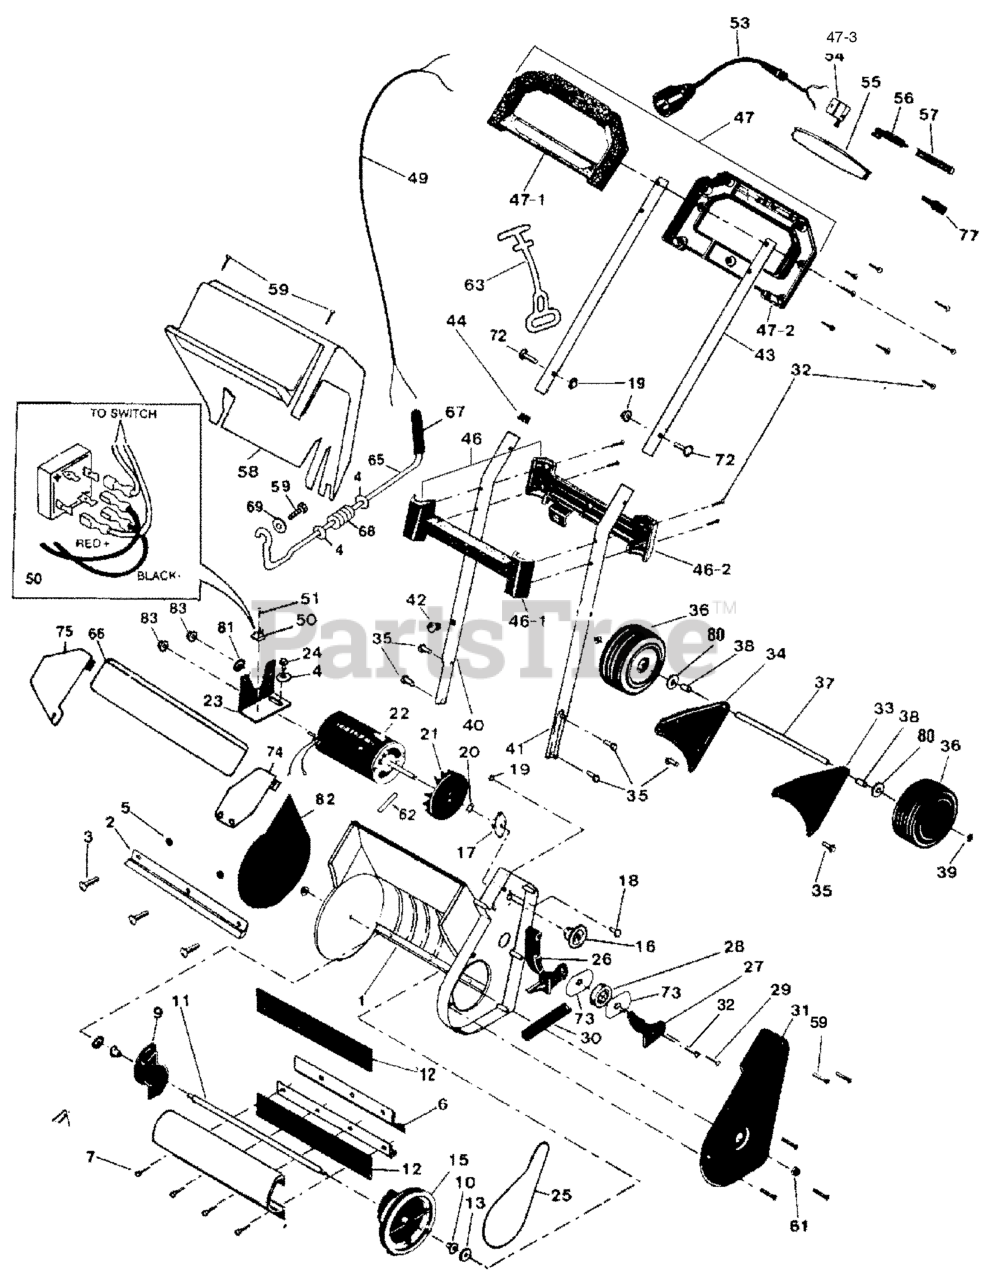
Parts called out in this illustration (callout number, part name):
1	Housing, Scoop
2	Blade, Scraper
4	Washer, Flat
5	Nut, 1/4-20
6	Segment, Drum
9	Cap, Drum End
10	Bearing, Bronze
11	Shaft, Paddle
12	Paddle, Auger
13	Washer, Flat
15	Pulley, Driven
16	Pulley, Drive
17	Bearing, Self Align
18	Screw, 1/4-20
19	Nut, 1/4-20
20	Ring, Retainer
21	Fan, Motor
22	Motor, 120V
23	Bracket, Motor Mount
24	Screw, 1/4-14x0.75
25	Belt, Drive
26	Arm, Idler
27	Bearing, Retainer Idler
28	Bearing, Ball
30	Spring Idler
31	Cover, Left Drive Housing
32	Screw
33	Bracket, Left Wheel
34	Bracket, Right Wheel
35	Screw
36	Wheel, 15"
38	Spacer, Wheel
39	Nut, Push On Cap
40	Handle, Right Lower
41	Handle, Left Lower
42	Bushing
43	Handle, Upper
44	Protector, Harness
45	Harness, Protector
46	Set, Handle Assist
46-1	Order Set
46-2	Order Set
47	Set, Handle Grip
47-1	Order Set
47-2	Order Set
47-3	Order Set
49	Harness, Wire
50	Rectifier, Full Wave
53	Connecting Lead
55	Bar, Switch
56	Lever, Switch
57	Spring, Switch
58	Cover, Motor
62	Pin, Grooved
63	Strain Relief, Cord
65	Rod, Discharge
66	Slider, Vane
67	Grip, Hand Vinyl
68	Spring, Actuator Rod
69	Washer, Flat
73	Retainer, Belt
74	Deflector, Outer
75	Deflector, Inner
77	Key, Hi-Pro
80	Washer, Flat
81	Grommet
82	Cover, Right Housing
